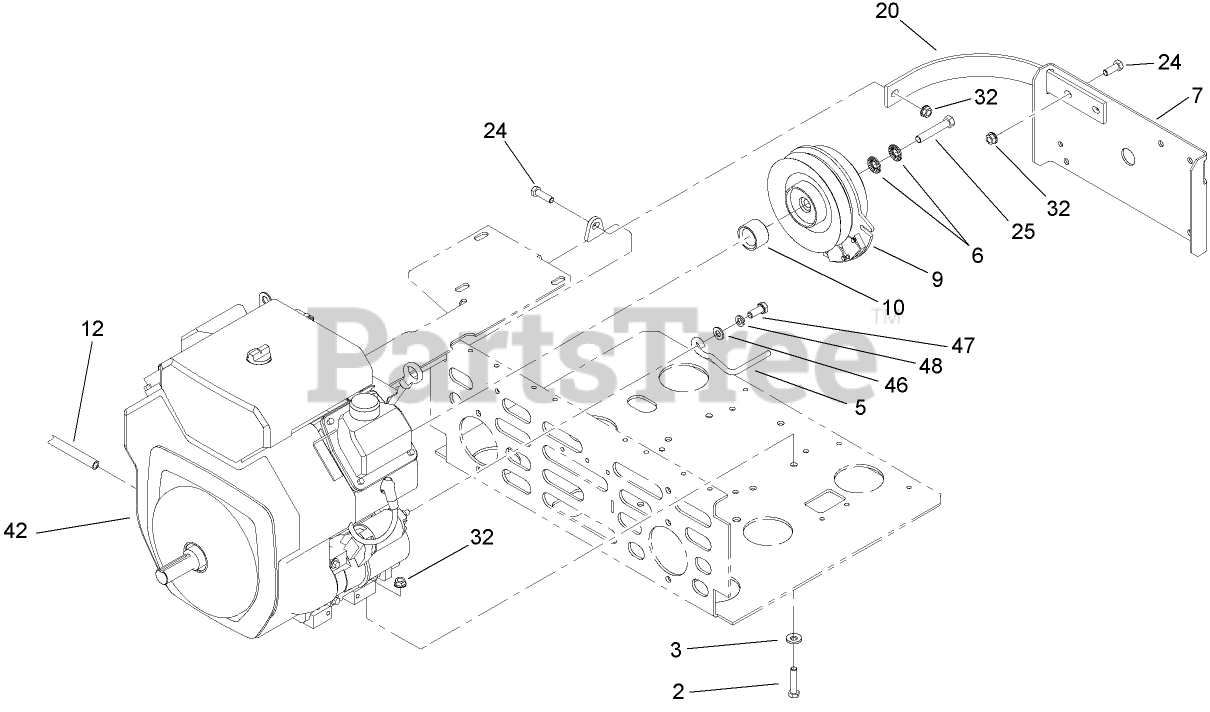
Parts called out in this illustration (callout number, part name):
2	SCREW-HH
3	WASHER-BELLEVILLE
5	ROD-BELT
6	WASHER-SPRING
7	GUARD-CLUTCH
9	CLUTCH
10	SPACER-CLUTCH
12	TUBE-DRAIN, OIL
20	STRAP-GUARD
24	SCREW-HH
25	SCREW-HH
32	NUT-HHF, WHIZ
46	WASHER-FLAT
47	SCREW-HH
48	WASHER-BELLEVILLE
